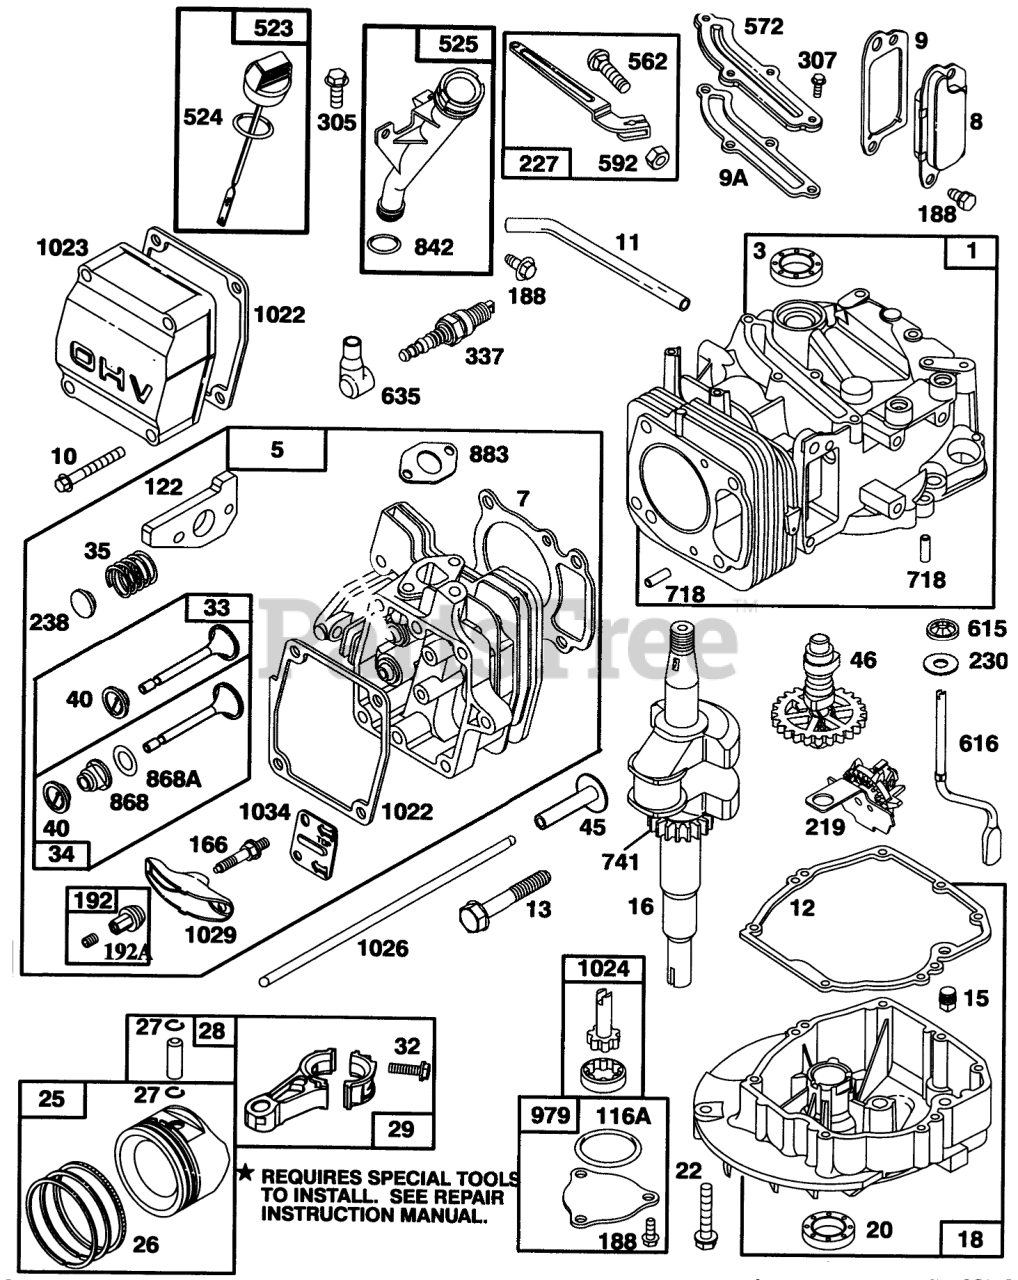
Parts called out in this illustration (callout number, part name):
1	CYLINDER ASSEMBLY
3	SEAL - OIL
5	CYLINDER HEAD
7	CYLINDER HEAD GASKET
8	BREATHER ASM
9	BREATHER GASKET
9A	GASKET-BREATHER
10	HEX HEAD SCREW
11	BREATHER TUBE
12	ENGINE BASE GASKET
13	CYLINDER HEAD SCREW
15	PIPE PLUG
16	CRANKSHAFT
18	ENGINE SUMP
20	SEAL-OIL
22	SCREW - ENGINE BASE
25	STD PISTON ASSEMBLY
26	STD RING SET
27	PISTON PIN LOCK
28	Pin Assy-Piston
29	CONNECTING ROD
32	Connecting Rod
33	EXHAUST VALVE
34	INTAKE VALVE
35	VALVE SPRING
40	SPRING RETAINER
45	VALVE TAPPET
46	CAM GEAR
116A	O RING SEAL
122	ADAPTER ASSEMBLY
166	ROCKER ARM STUD
188	SCREW - SEM
192	NUT - HEX SPECIAL
192A	Screw-Set
219	GOVERNOR/OIL SLINGER
227	GOVERNOR LEVER ASSEMBLY
230	WASHER
238	VALVE CAP
305	SCREW - HEX HEAD
307	SCREW - SEM
337	PLUG-SPARK
523	DIPSTICK-OIL
524	O-RING
525	OIL FILLER TUBE
562	GOVERNOR LEVER BOLT
572	BAFFLE - CYCLINDER
592	HEX NUT
615	FASTENER
616	GOVERNOR CRANK
635	SPARK PLUG ELBOW
718	DOWEL - SLEEVE
741	TIMING GEAR
842	O-RING
868	SealAssy-Valve
868A	Seal-Valve
883	EXHAUST GASKET
979	OIL PUMP COVER
1022	ROCKER COVER GASKET
1023	Cover-Valve
1024	OIL PUMP
1026	PUSH ROD
1029	ROCKER ARM
1034	PUSH ROD GUIDE
